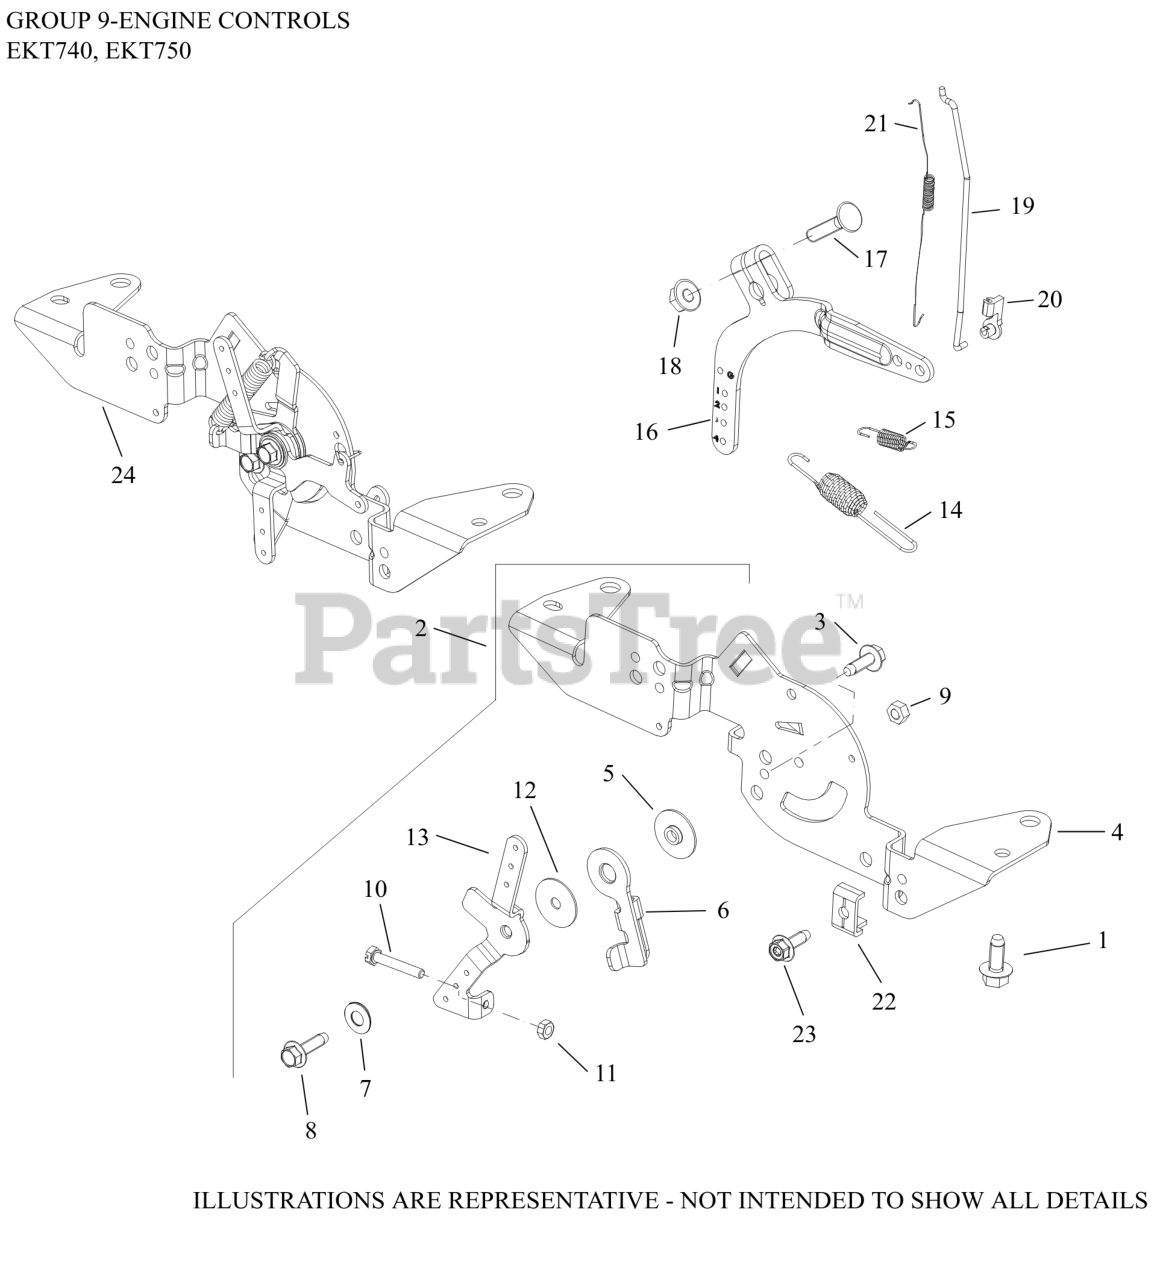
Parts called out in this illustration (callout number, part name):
1	SCREW, THREAD FORMING
2	SPEED CONTROL, ASSEMBLY
3	SCREW, THREAD FORMING
4	BRACKET, SPEED CONTROL
5	SPACER, CONTROL ASSEMBLY
6	LEVER, THROTTLE ACTUATOR
7	WASHER, SPRING 1/4"
8	SCREW, THD FRM-USE 25 086 473-S
9	NUT, LOCK M5X.8
10	SCREW, SLT HD CAP M4X0.7X25
11	NUT, M4X0.7
12	WASHER, FLAT 5 MM
13	LEVER, THROTTLE CONTROL
14	SPRING, GOVERNOR (ORANGE)
15	SPRING, GOVERNED IDLE
16	LEVER, GOVERNOR - (#2409069S)
17	BOLT, RD HD SQ NECK M6X1.0X25
18	NUT, FLG M6X1.0
19	LINKAGE, THROTTLE
20	BUSHING, THROTTLE LINKAGE
21	SPRING, LINKAGE
22	CLAMP, CABLE-(#2523753S)
23	SCREW, THREAD FORMING
